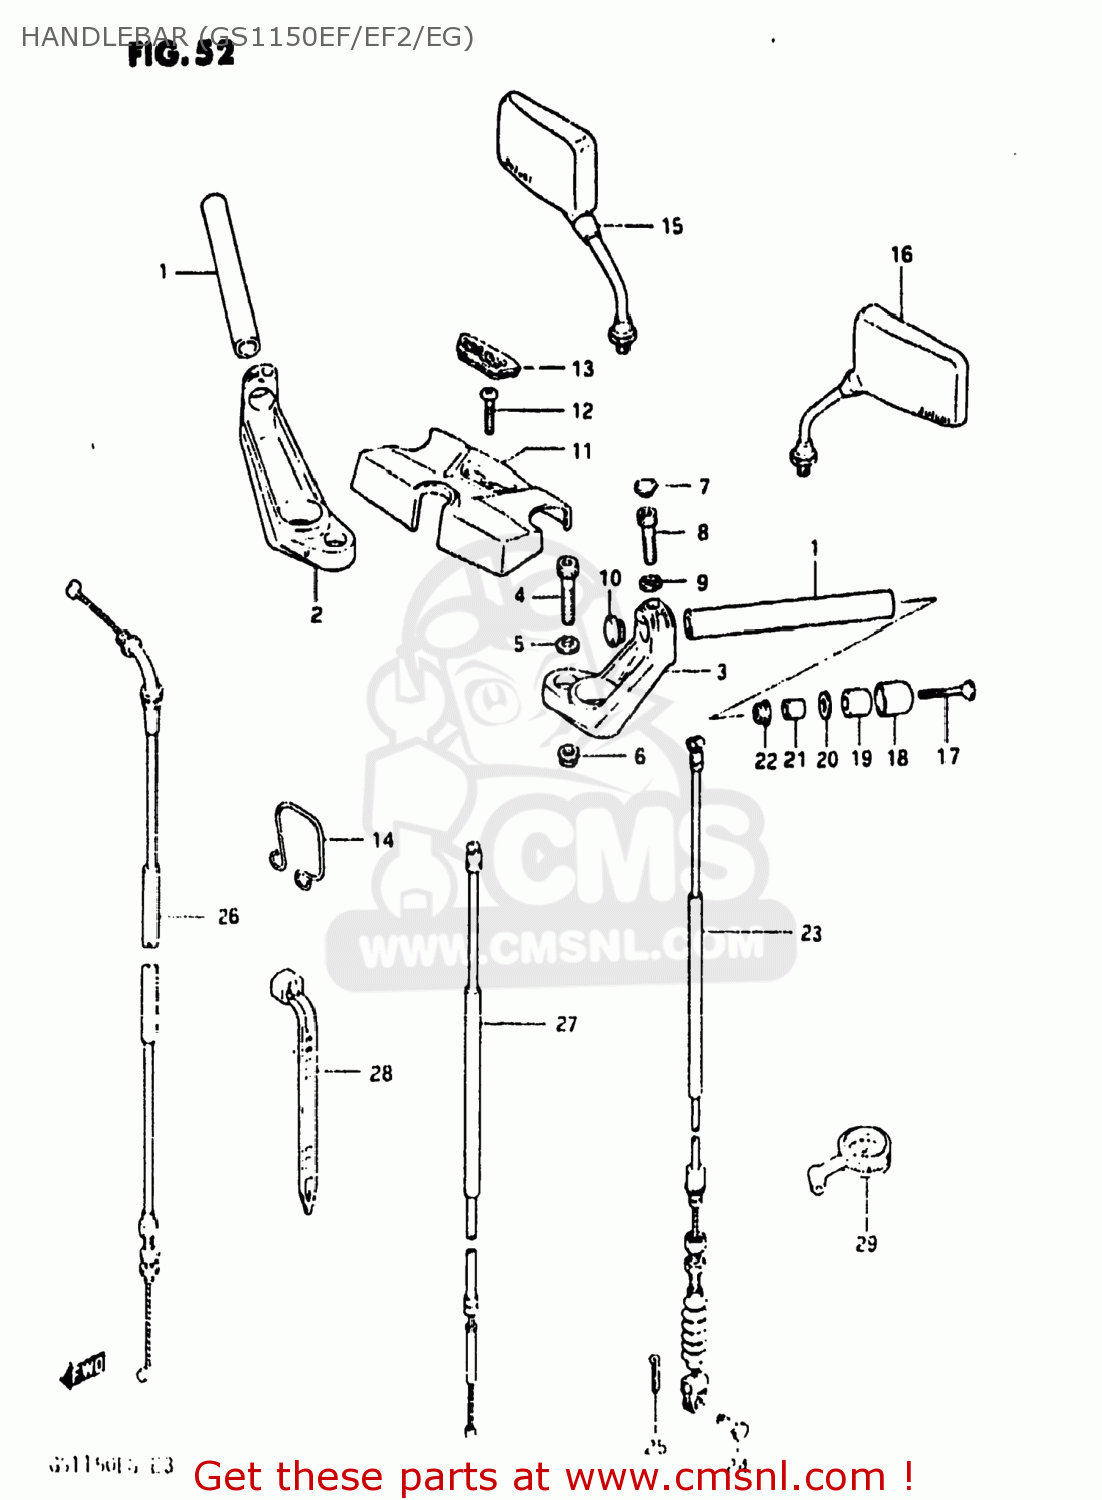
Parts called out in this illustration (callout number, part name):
1	HANDLEBAR,RIGHT
2	HOLDER,HANDLEBAR,RIGHT
3	HOLDER,HANDLEBAR,LEFT
4	BOLT(10X50)
5	WASHER
6	NUT 10MM
7	CAP(OD:14.5)
8	BOLT 8X35
9	WASHER
10	CAP,GRIP END
11	PAD,HANDLE
12	SCREW
13	CAP,HANDLE PAD
14	GUIDE,CABLE/HARNESS
15	MIRROR ASSEMBLY,REAR VIEW
16	MIRROR ASSEMBLY,REAR VIEW
17	SCREW 6X55
18	CAP,BALANCER
19	BALANCER,HANDLEBAR
20	SPACER,BALANCER
21	EXPANDER,HANDLE BALANCER
22	NUT
23	CABLE ASSY,CLUTCH
24	PIN(L:15)
25	PIN
26	CABLE ASSY,THROTTLE
27	CABLE COMP,STARTER
28	CLAMP(L:165)
29	GAUGE ASSY,AIR PRESSURE
